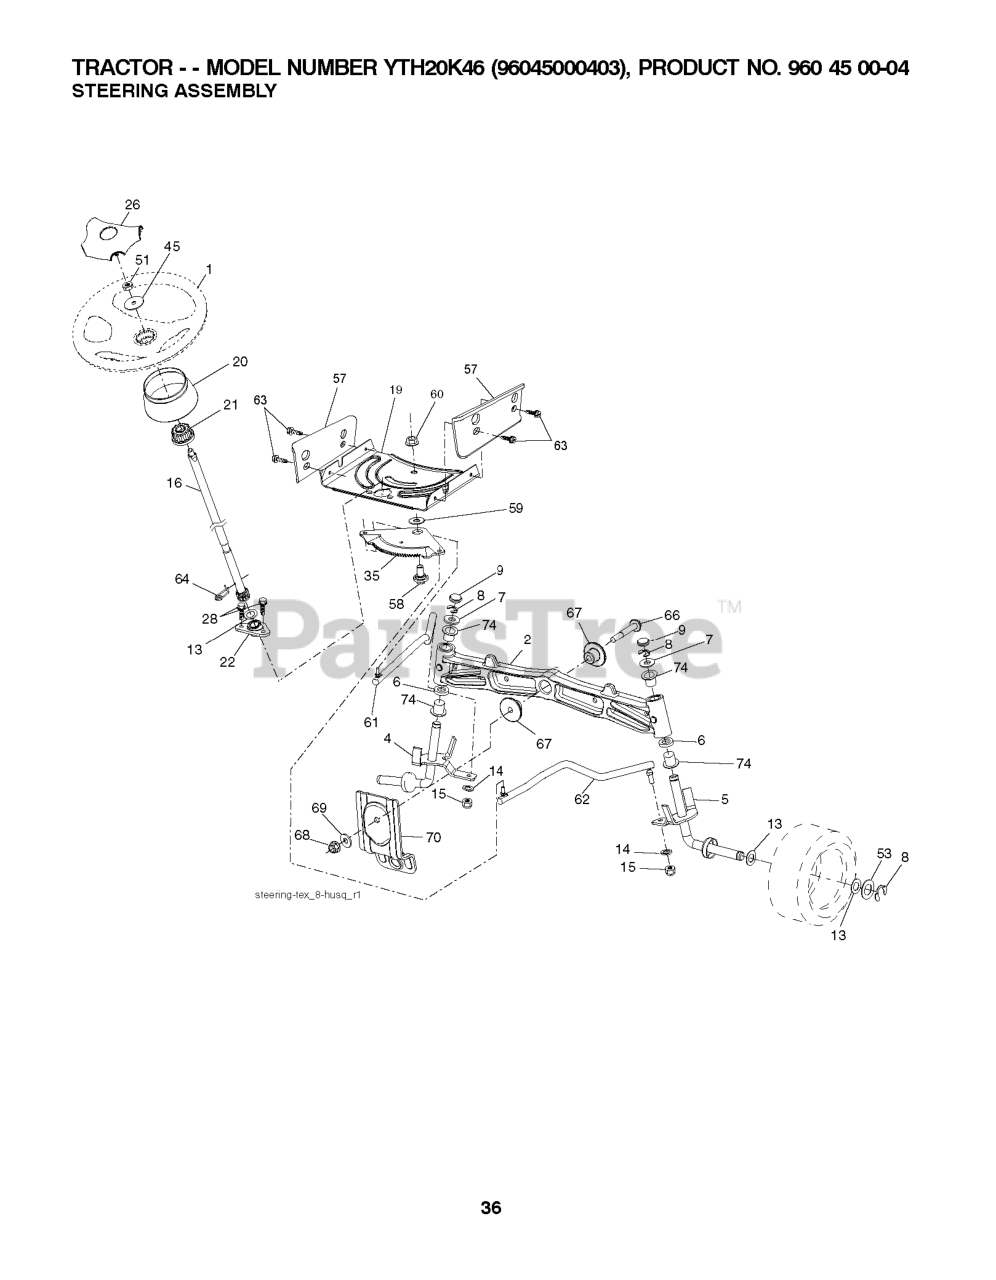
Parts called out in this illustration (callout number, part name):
1	WHEEL.STEERING.LEGEND2.GRY
2	AXLE.CAST.IRON
4	SPINDLE.WELDED.LH.15"TEX
5	SPINDLE.WELDED.RH.15"T
6	THRUST WASHER
9	CAP.SPINDLE.BLACK
14	WASHER, LOCK 3/8
15	NUT CROWNLOCK 3/8-24
16	SHAFT, STEERING
19	PLATE.STEER.DDL.NLT/NG
21	ADAPTER, WHEEL STNG..
22	BUSHING.ASM.STEERING.A
26	INSERT.CAP.STRG.WH.GRAY
28	SCREW, 3/8-16X3/4
35	GEAR.SECTOR.PLATE.DDL.
45	WASHER 9/16"ID, 2 3/8"OD
51	NUT.HEX.1/2-20
53	WASHER.HARDENED
57	BRACKET.UPSTOP.TEX
58	BOLT.SHOULDER.SECTOR.P
59	WASHER.THURST.SECTOR.S
60	NUT FLANGE LOCK 5/8-11
61	DRAGLINK.LH.BALLSTUD.D
62	DRAGLINK.RH.BALLSTUD.D
63	SCREW
64	RETAINER.CLIP.SPRING.S
66	BOLT HEX FGHD 7/16-14 X 3 SERR
67	BUSHING.PM.FRONT AXLE
68	NUT.LOCK.FLANGE.7/16
69	WASHER.1.5X.505X.118
70	BRKT.DECK.SUSPENSION.F
74	BRNG T
